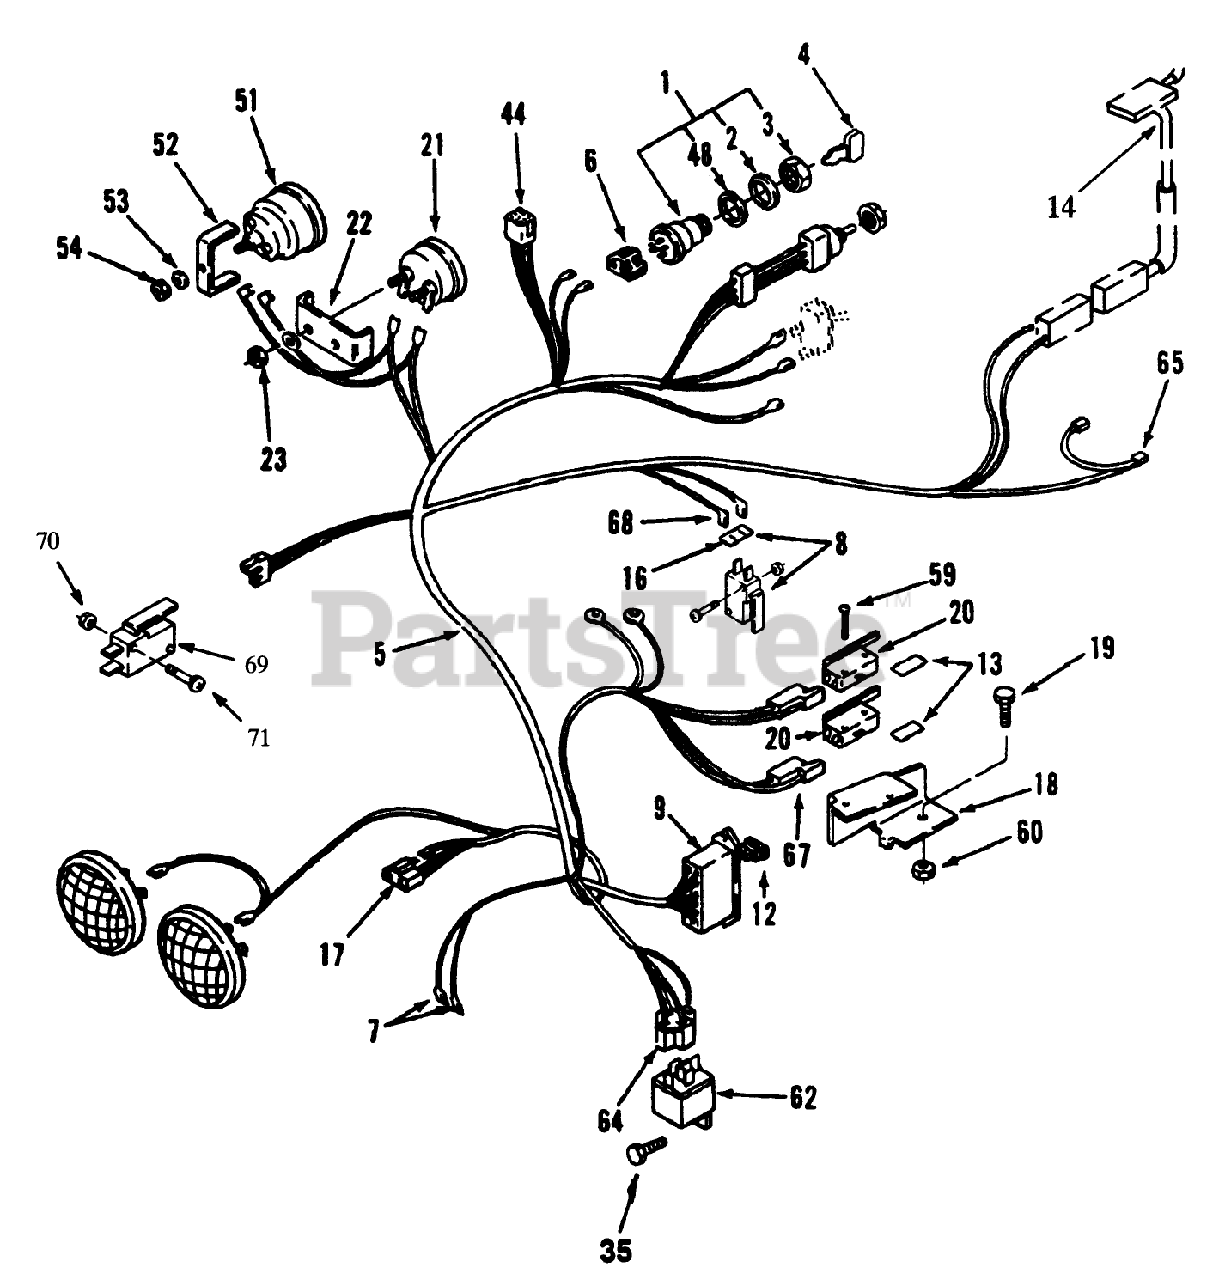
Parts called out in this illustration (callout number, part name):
4	KEY-IGNITION
7	TERMINAL 10
8	SWITCH - CLUTCH
12	FUSE-BLADE, 15 AMP
13	BARRIER - SWITCH
14	SWITCH-SEAT
16	SHIELD-DIRT SPST
17	5-CONTACT CONN BODY
19	SCREW-HWH
20	SWITCH
21	VOLTMETER
22	CLAMP-MOUNTING
23	NUT-HEX
35	SCREW-PAN
48	WASHER
52	CLAMP-HOUR METER
53	WASHER-LOCK / EXT
59	SCREW-PHL 4-40X1 1/4
62	RELAY
64	TERMINAL 10
65	Sur-Plug
68	Terminal
69	SWITCH
71	Screw
